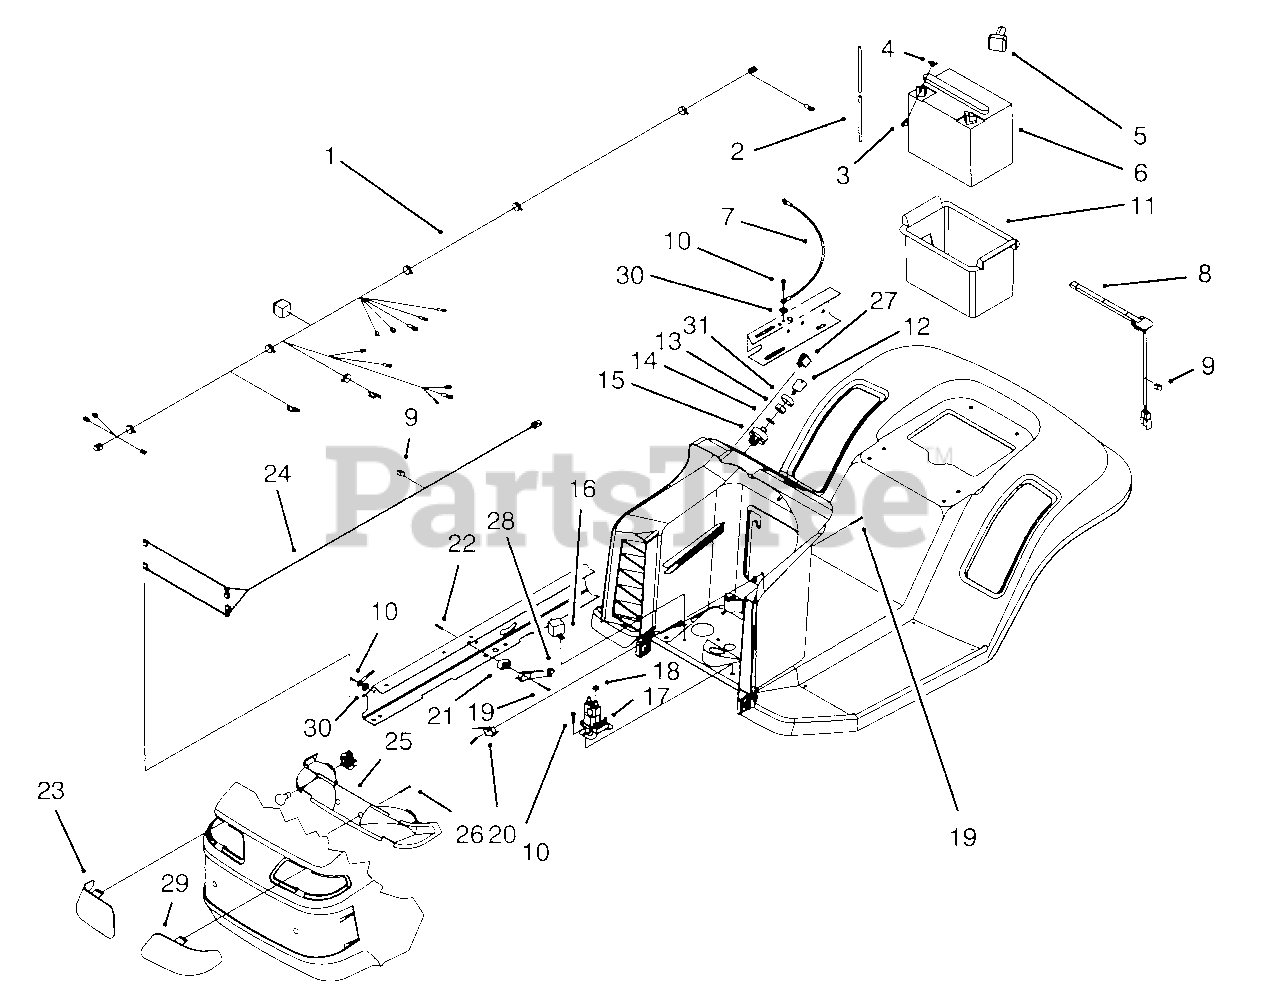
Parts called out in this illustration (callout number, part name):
1	Harness-Wire
2	Vent-Tube
3	Screw-Hex Hd. Cap
5	Boot-Battery Terminal
6	Battery-7 Plate
7	Cable-Battery Negative
8	Switch-Seat
9	Clip-Wire Retainer
10	Screw-Hex Hd. Thr'd Forming
11	Box-Battery
12	Key-Ignition
14	Washer-Lock
15	Switch-Ignition (Incl. Ref. #13 & 14)
17	Solenoid
18	Nut-Keps
19	Screw-Phillips Hd.
20	Switch-Micro
21	Spacer-Microswitch
23	Lens-R.H.
24	Harness-Wire
25	Reflector & Lamp
26	Screw-Plastite
27	Switch-Rocker
28	Seal-Plunger
29	Lens-L.H.
30	Washer-Lock
